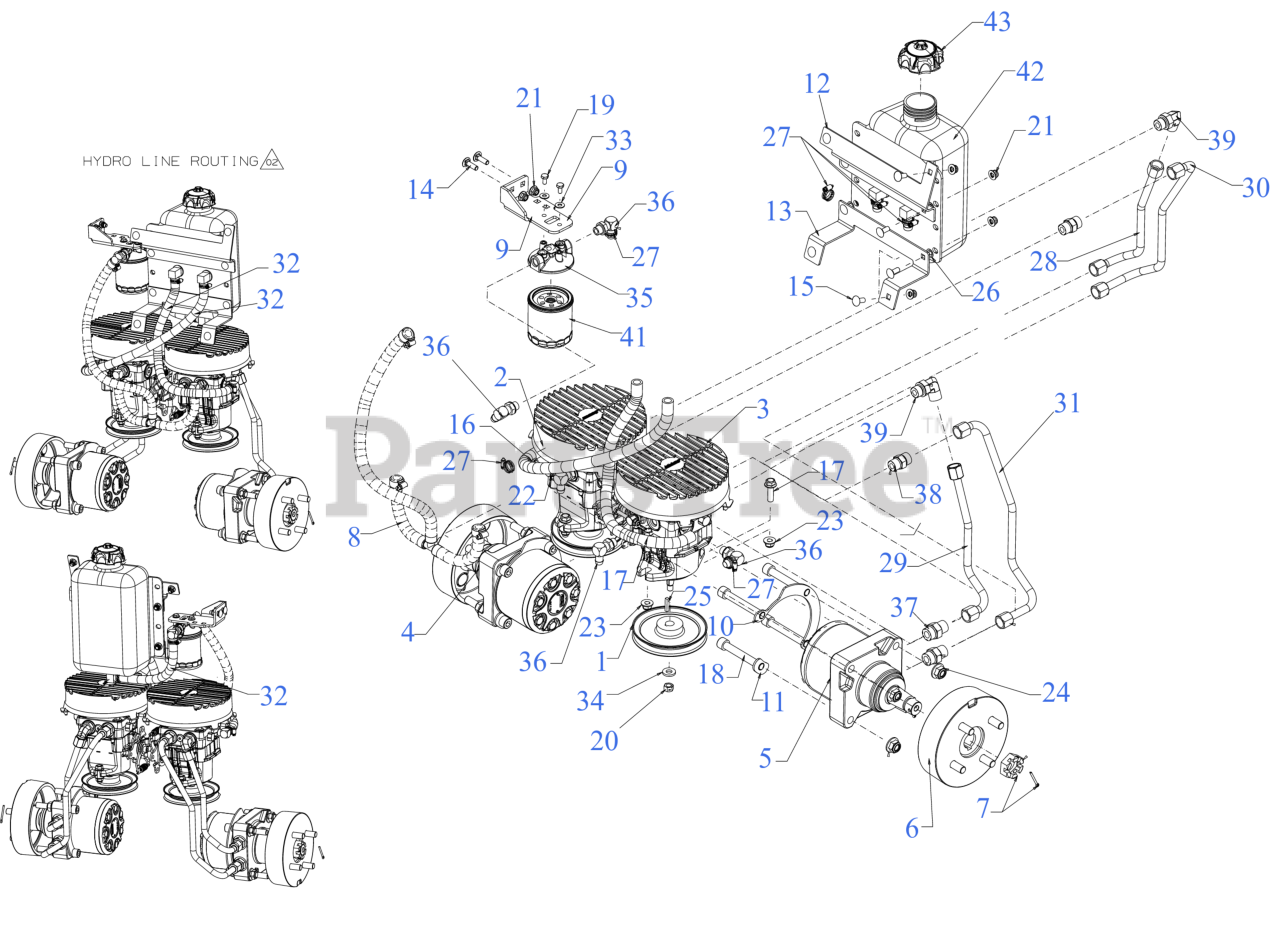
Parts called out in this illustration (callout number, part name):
1	PULLEY-HYDRO PUMP
2	HYDRO PUMP (LH)
3	HYDRO PUMP (RH)
4	HYDRO MOTOR W/O BRAKE (LH)
5	HYDRO MOTOR W/O BRAKE (RH)
7	HUB MOUNT HARDWARE
8	HYDRO DRAIN HOSE
8	HOSE CLAMP
9	FILTER MOUNT BRACKET
10	WHEEL MOTOR SHIM PLATE
11	WHEEL MOTOR LOWER SHIM PLATE
12	OIL RESERVOIR BRACKET
13	OIL RESERVOIR BRACKET (LOWER)
14	CARRIAGE BOLT 5/16-18 x 1.00
15	CARRIAGE BOLT 5/16-18 x .75
16	SCREW 1/4-20 x 2 GR5
17	SCREW 3/8-16 x 1.25 GR5
18	HEX CAP SCREW 1/2"-13x3.5
19	SCREW 1/4-20X.5 GR5
21	FLANGE LOCK NUT 5/16-18
22	FLANGE LOCK NUT
25	SQUARE KEY 3/16 x 1.00
27	HOSE CLAMP .75 ID
28	HYDRO TUBE (OUTSIDE) (LH)
29	HYDRO TUBE (OUTSIDE) (RH)
30	HYDRO TUBE (INSIDE) (LH)
31	HYDRO TUBE (INSIDE) (RH)
32	HYDRAULIC BULK HOSE 12"
32	HYDRAULIC BULK HOSE 19"
33	FLAT WASHER
34	FLAT WASHER
35	OIL FILTER ADAPTER
36	ELBOW FITTING
37	HYDRO FITTING 8 ORFS x 10 ORB
38	HYDRAULIC FITTING
39	HYDRAULIC ELBOW ADAPTOR
41	HYDRAULIC FILTER
42	HYDRO OIL TANK (1 GAL)
43	HYDRO OIL TANK CAP
